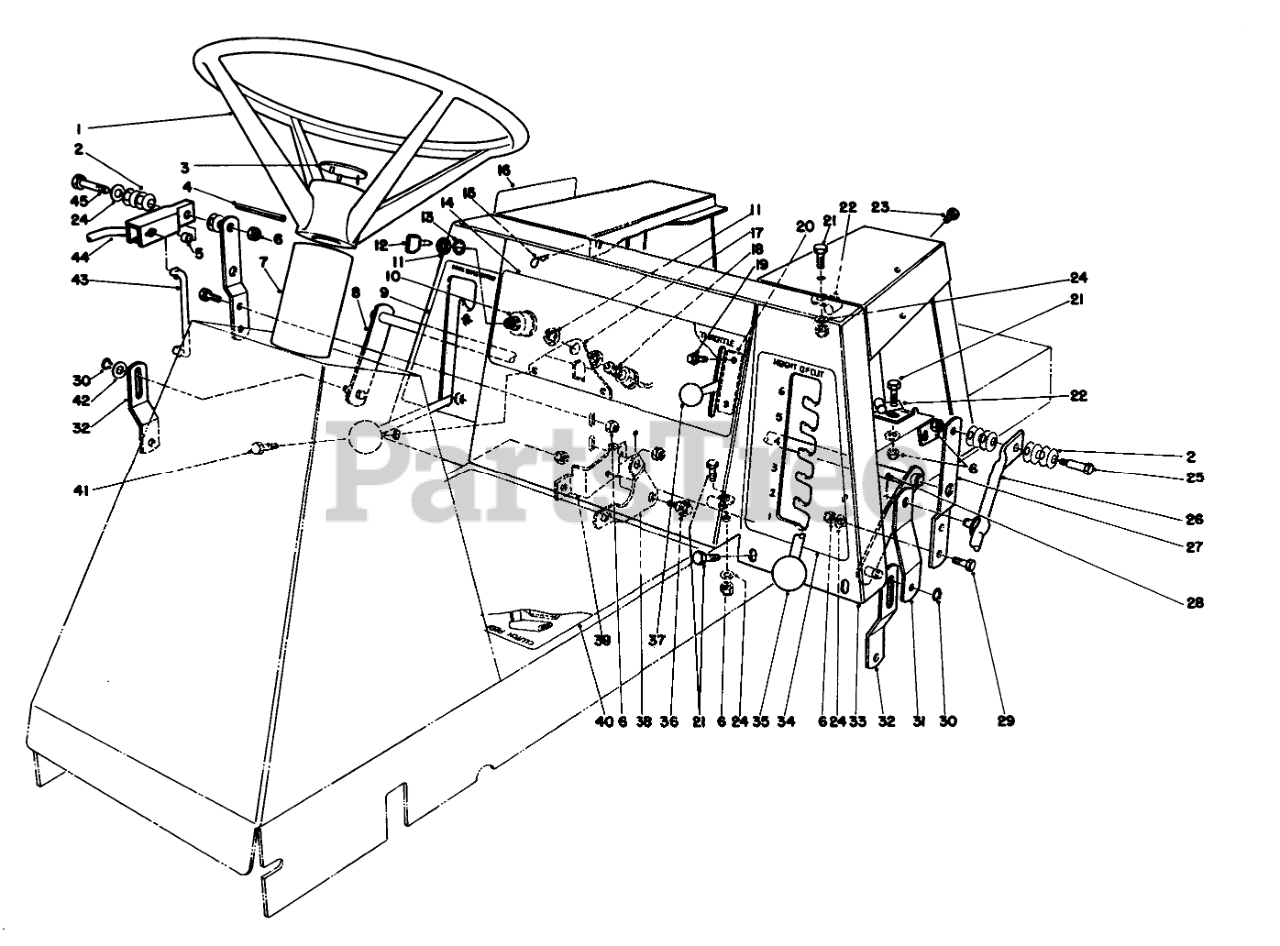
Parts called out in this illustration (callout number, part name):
1	Steering Wheel Assembly (Incl. Ref. #3)
2	WASHER-BELLEVILLE
3	Cap-Steering Wheel
4	PIN-ROLL
5	SPACER
6	NUT-LOCK, NI
7	STRG. SHAFT COVER
8	Arm
9	DECK ENGAGE DECAL
10	Switch-Ignition (Incl. Ref. #11-13)
11	NUT-HH
12	KEY-IGNITION
13	WASHER-TOOTH, INTERNAL
14	IGN & THROTTLE DECAL
15	PIN-COTTER
16	Decal Shift Pattern
17	SWITCH MT BRKT
18	Switch-Deck (Incl. Ref. #11)
19	SCREW-HWHTF
20	Control-Throttle (Incl. Ref. #37)
21	SCREW-HH
22	CLAMP
23	SCREW-HH
24	WASHER-PLAIN
25	BOLT-SHOULDER
26	HOC LEVER WA B
27	Bracket
28	PIN-COTTER
29	SCREW-HH
30	RING-RETAINING
31	HOC ENGAGE BRKT R
32	Link-Deck Suspension
33	Body-Seat
34	HOC DECAL
36	SCREW-SHOULDER
37	Knob
38	DECK ENGAGE BELLCRANK
39	BELLCRANK MTG BRKT
40	INSTRUCTION DECAL
41	SCREW-HH
42	WASHER-FLAT
43	BELLCRANK LINK(PLTD)
44	SHIFT LEVER WA B
45	SCREW-HH
